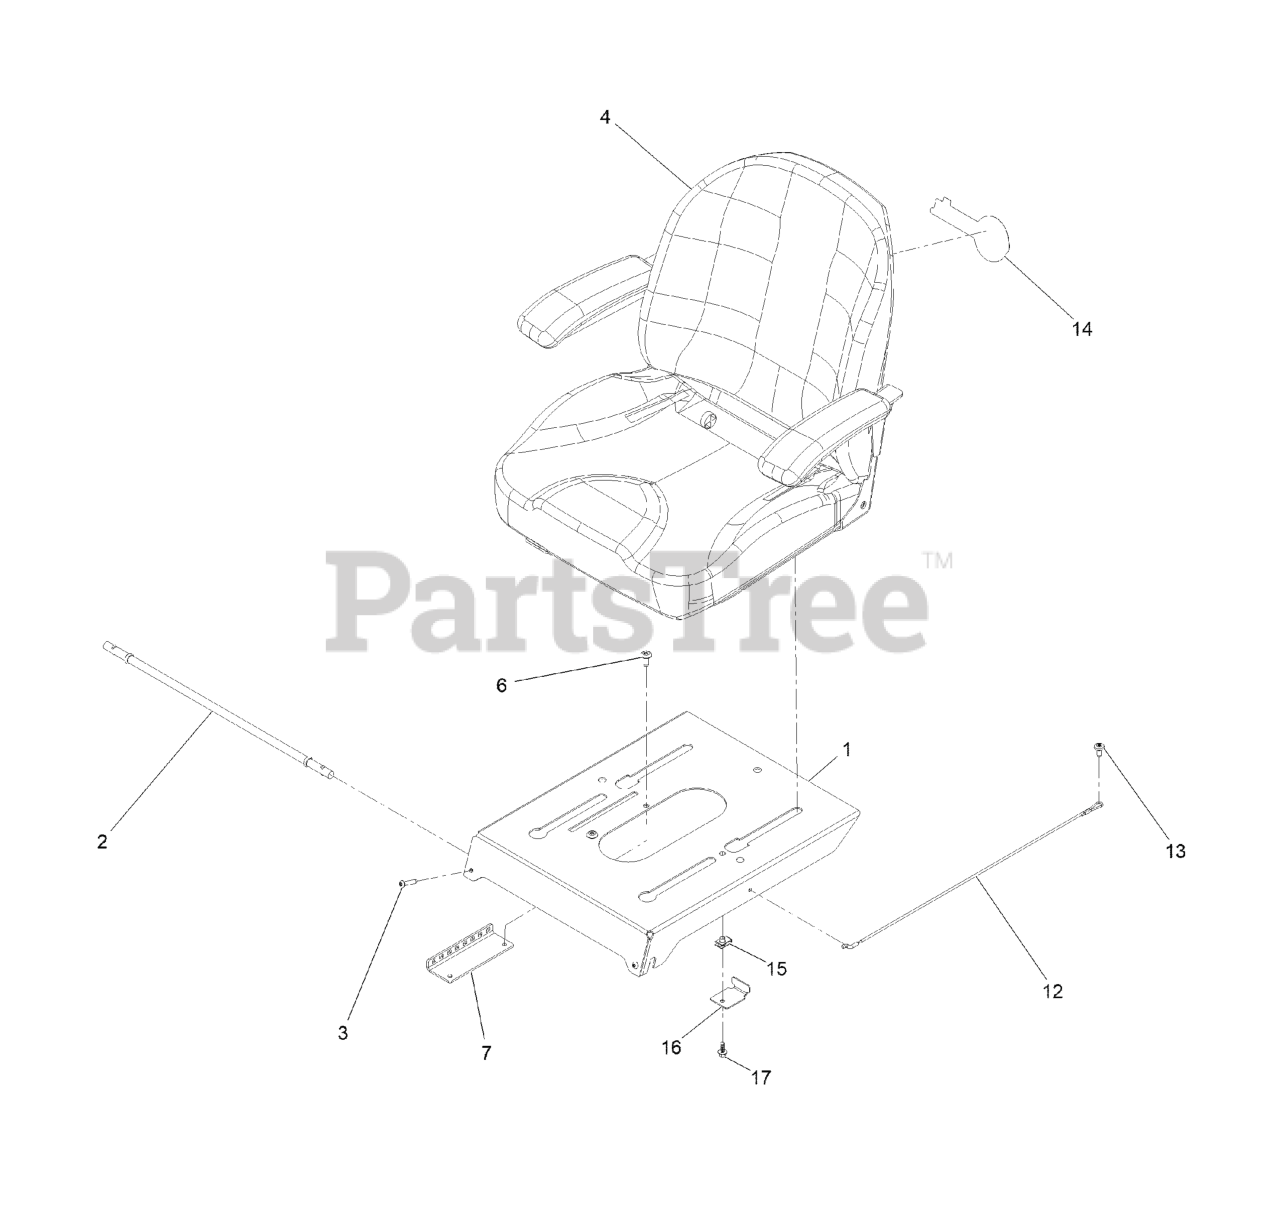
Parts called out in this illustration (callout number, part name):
2	ROD-PIVOT
3	SCREW-TTH, THREAD ROLLING
4	SEAT ASM, EXMARK
7	BRACKET-LATCH, SEAT
12	CABLE-LANYARD
13	SCREW-SHOULDER
14	DECAL-EXMARK LOGO
16	Bracket-Stop, Seat
17	SCREW-HHF
